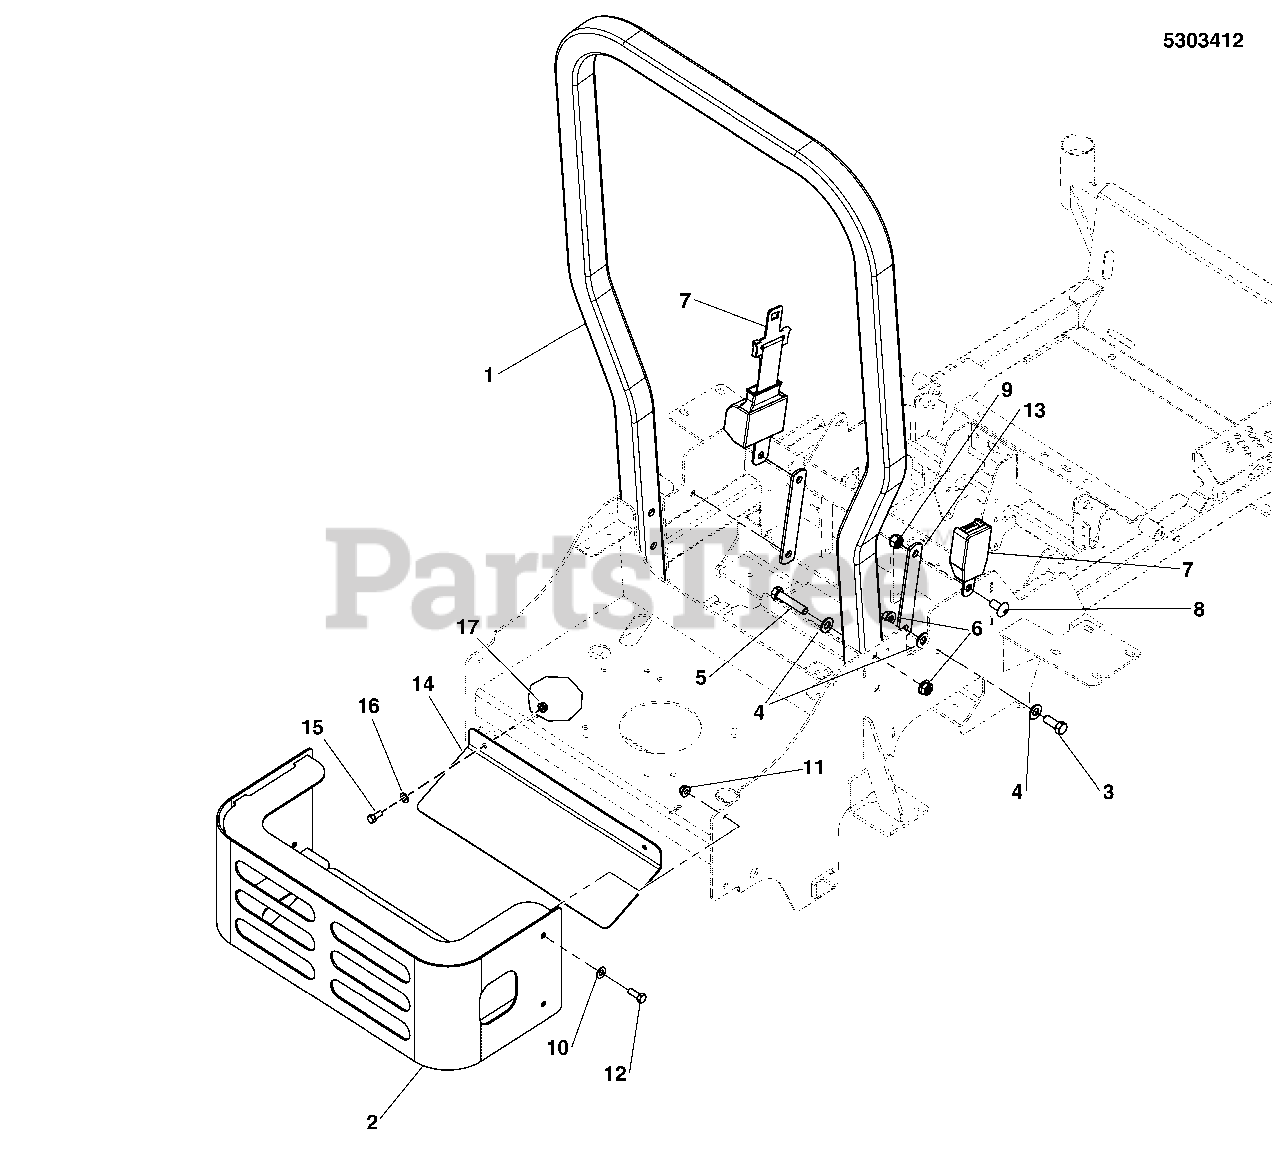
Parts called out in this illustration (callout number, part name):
1	ROPS (Call 1-800-933-6175 x708 if replacing a ROPS)
2	WELD, BUMPER, S550 - RED
2	WELD, BUMPER, 550Z - RED
3	BOLT, 1/2-13 X 1-1/4 GD5 YZ
4	WASHER, 1/2 SAE
5	BOLT, 1/2-13 X 2-1/2" GD5 CZ
6	NUT, 1/2-13 HEX NYLOCK FLANGE
7	SEAT BELT, RETRACTING - ASSM
8	SCREW, 1/2-13 X 1.00, SHCS
9	NUT, 1/2-13 HEX NYLON LOCK
10	WASHER, 3/8 SAE
10	WASHER, 1/2" SAE
11	NUT, Hex Flange, Nylock, 3/8-16
11	NUT, 1/2-13 NYLOCK FLANGE
12	BOLT, 3/8-16 X 1 GD5 YZ
12	BOLT, 1/2-13 X 1-1/4" GD5
13	BAR, MOUNT, SEAT BELT, IS700Z - BLK
14	PLATE, HEAT SHIELD, 550Z - BLK
15	BOLT, 5/16-18 X 3/4 GD5
16	WASHER, 5/16 SAE
17	NUT, 5/16-18 HEX NYLOCK FLANGE
